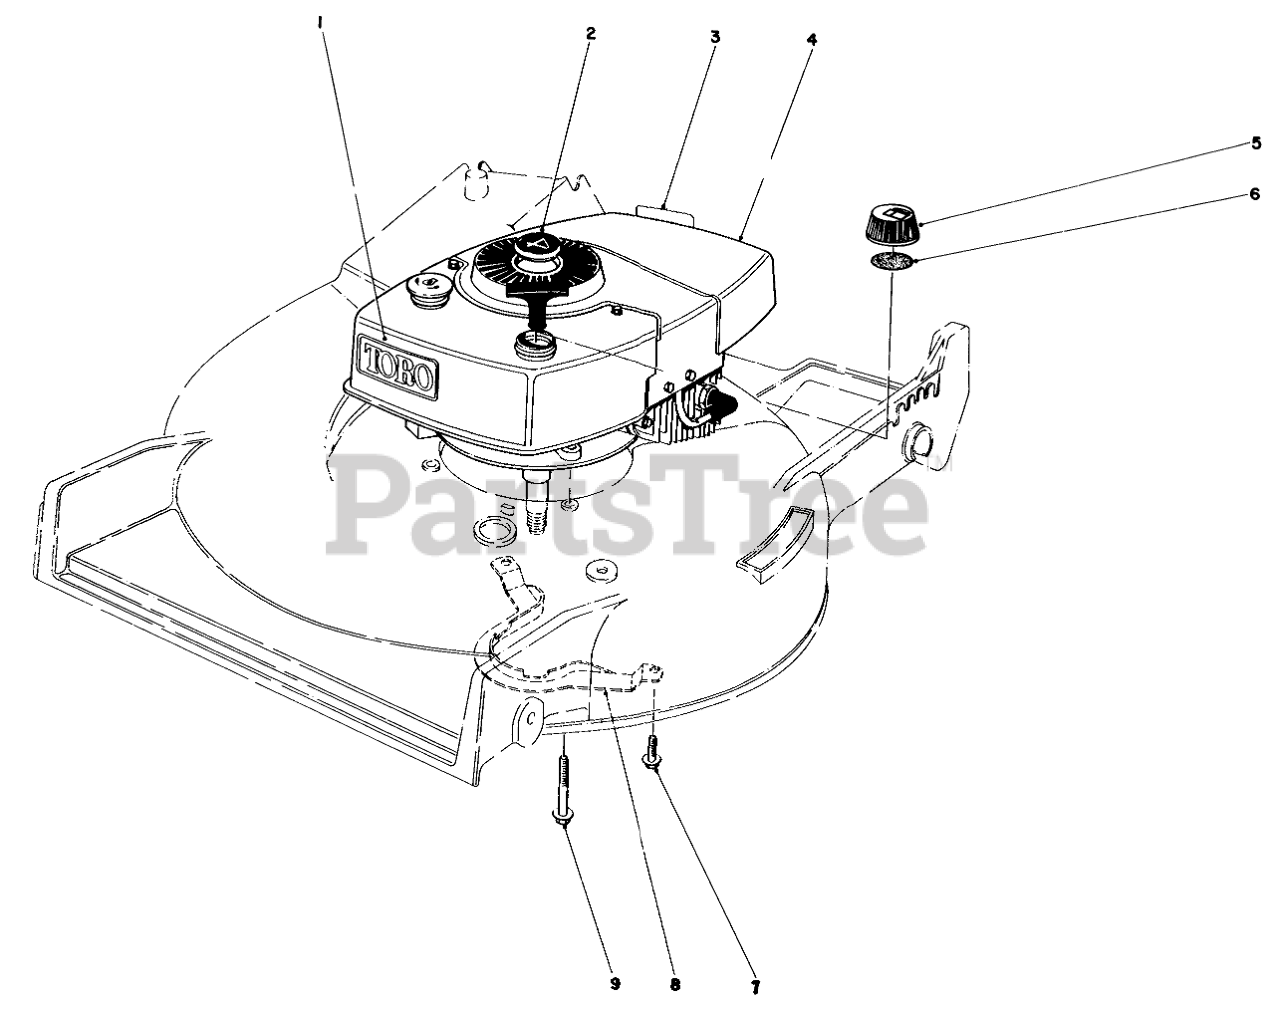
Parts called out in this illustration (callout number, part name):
1	Decal Tow
2	PLUG BUTTON
3	Decal-Maintenan
4	Engine
5	Gas Cap Assembly (Incl. Ref. #6)
6	GAS CAP GASKET
7	Screw
8	BELT GUIDE
9	3/8-16 X 2 CAPSCREW
